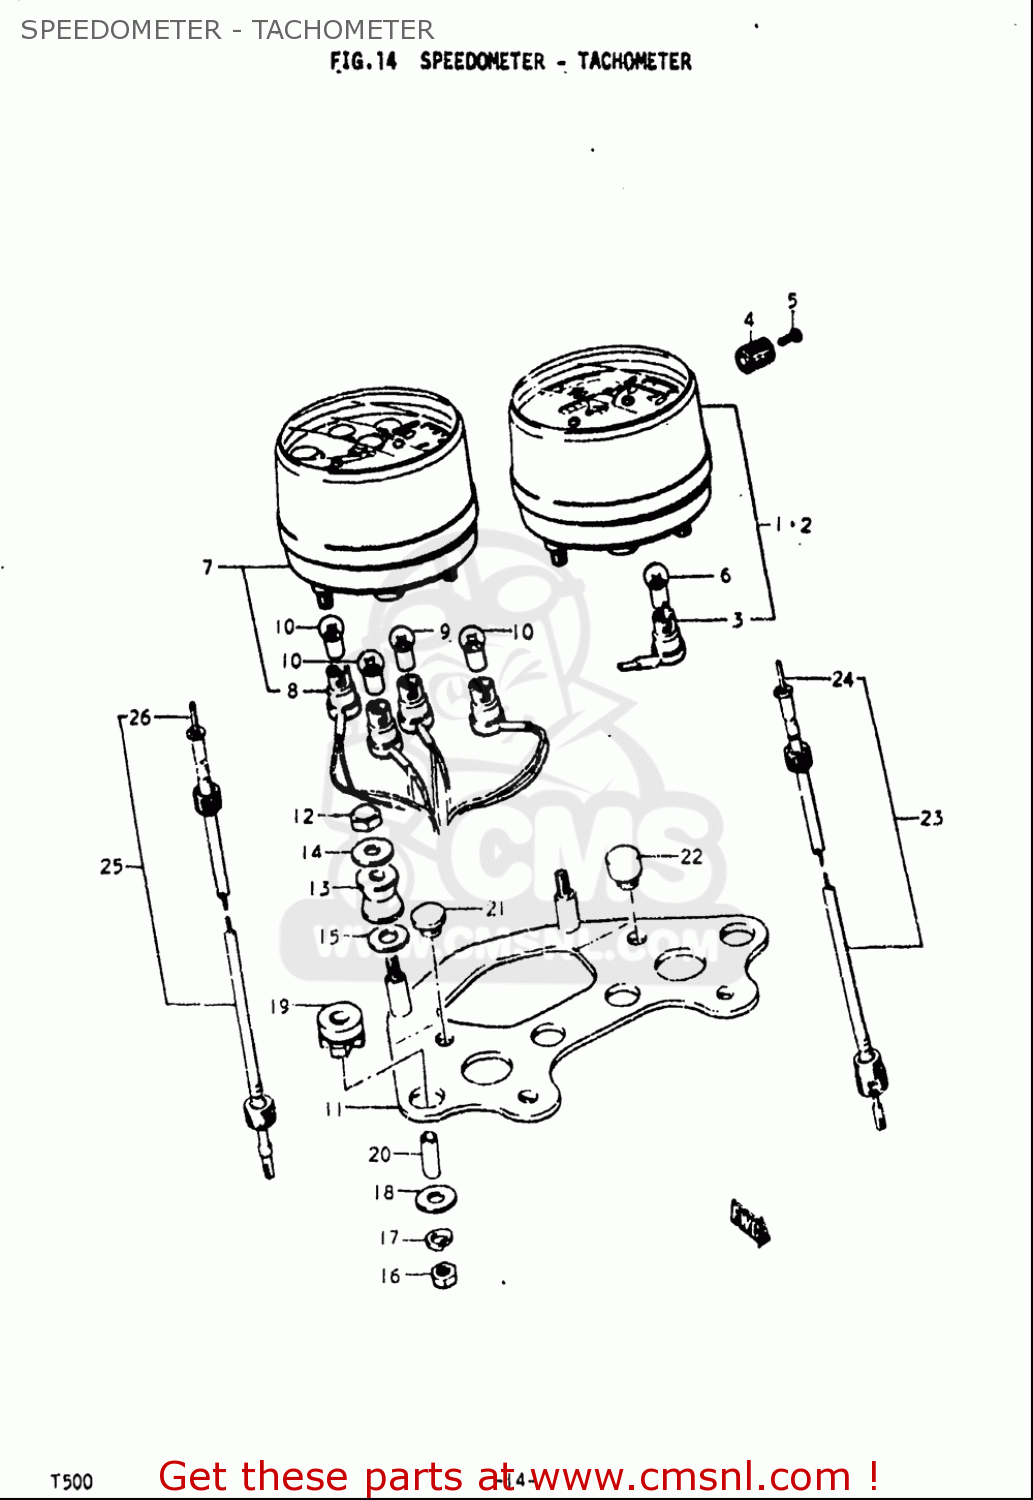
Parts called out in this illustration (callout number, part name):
5	SCREW(2X6)
6	BULB(12V3.4W,STANLEY,A72A)
9	BULB(12V1.7W,A71A)
10	BULB(12V3.4W,STANLEY,A72A)
12	NUT
13	CUSHION
14	WASHER(6.5X18X1.6)
15	WASHER
16	NUT
17	WASHER,LOCK
18	WASHER(6.5X18X1.6)
19	CUSHION,METER NO.1
23	CABLE ASSY,SPEEDOMETER
25	CABLE ASSY,TACHOMETER
26	CABLE ASSY,TACHOMETER
